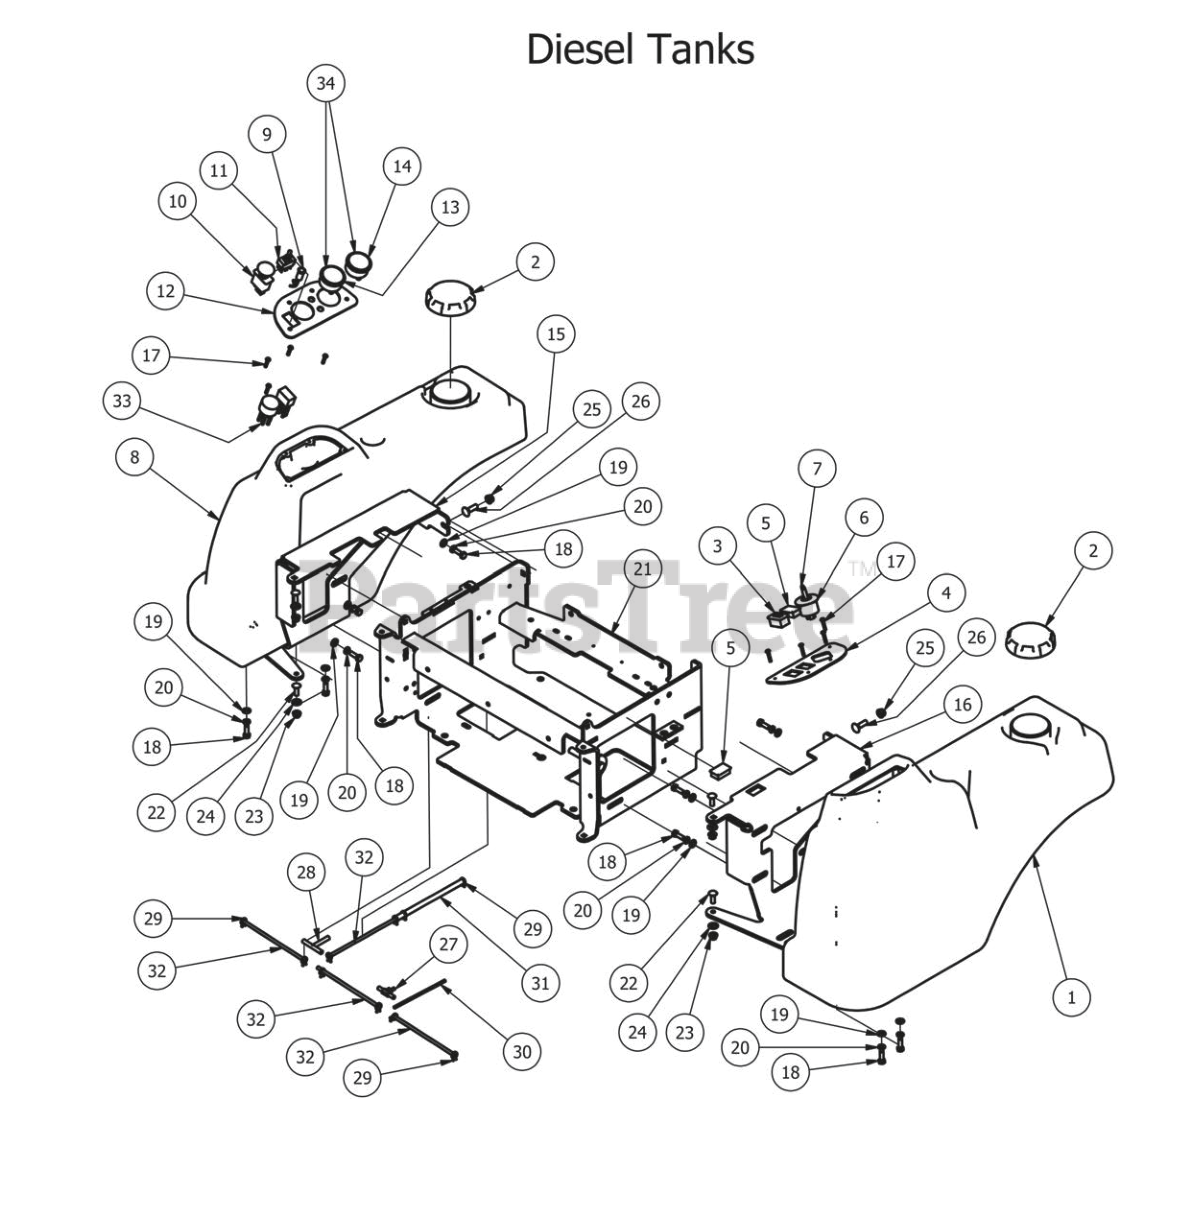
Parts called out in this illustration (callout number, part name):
1	Left Fuel Tank with Fender
2	Diesel Fuel Cap -3.5 inch Neck
3	Hour Meter
4	Control Panel (Left)
5	Light Plug
6	Ignition Switch
7	Ignition Key
8	Right Fuel Tank with Fender
10	PTO Engager
11	Deck Lift Joystick
12	Diesel Control Panel Right 2012
13	2" Water Temperature Gauge
14	2" Oil Pressure Gauge
15	Left Tank Support AOS
16	Right Tank Aupport AOS
17	10-32 x 1 Button Head Bolt
18	5/16" x 1" Bolt
19	5/16" Flat Washer
20	5/16" Lock Washer
21	Diesel Seat Frame
22	5/16" x 1" Carriage Bolt
23	5/16" Flange Nut
24	.360 ID Plastic Washer
25	3/8" Nylock Flange Nut
26	3/8" x 1 1/4" Carriage Bolt
27	Brass fuel line T
28	fuel line T
29	1/4 fuel clamp
30	3/16 Fuel Line
31	5/16" fuel line hose
32	1/4" fuel line hose
33	Wiring Harness -35 & 28 Diesel
34	Pigtail-2" Faria Gauge -2012 & up (Used For the water and Oil Gauges)
